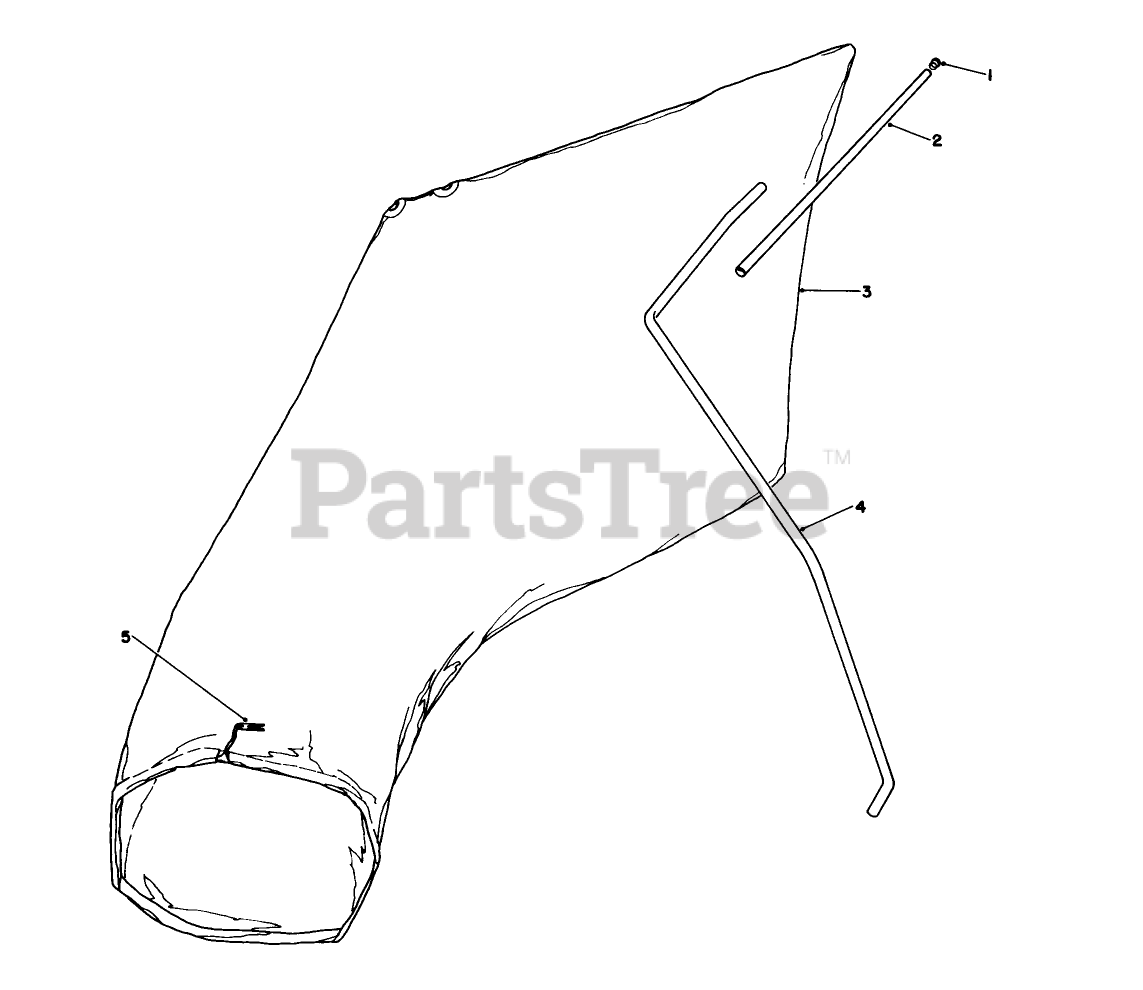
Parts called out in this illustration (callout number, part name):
2	BAG HANGER TUBE
4	HANGER ROD
5	BAG CORD FASTENER
